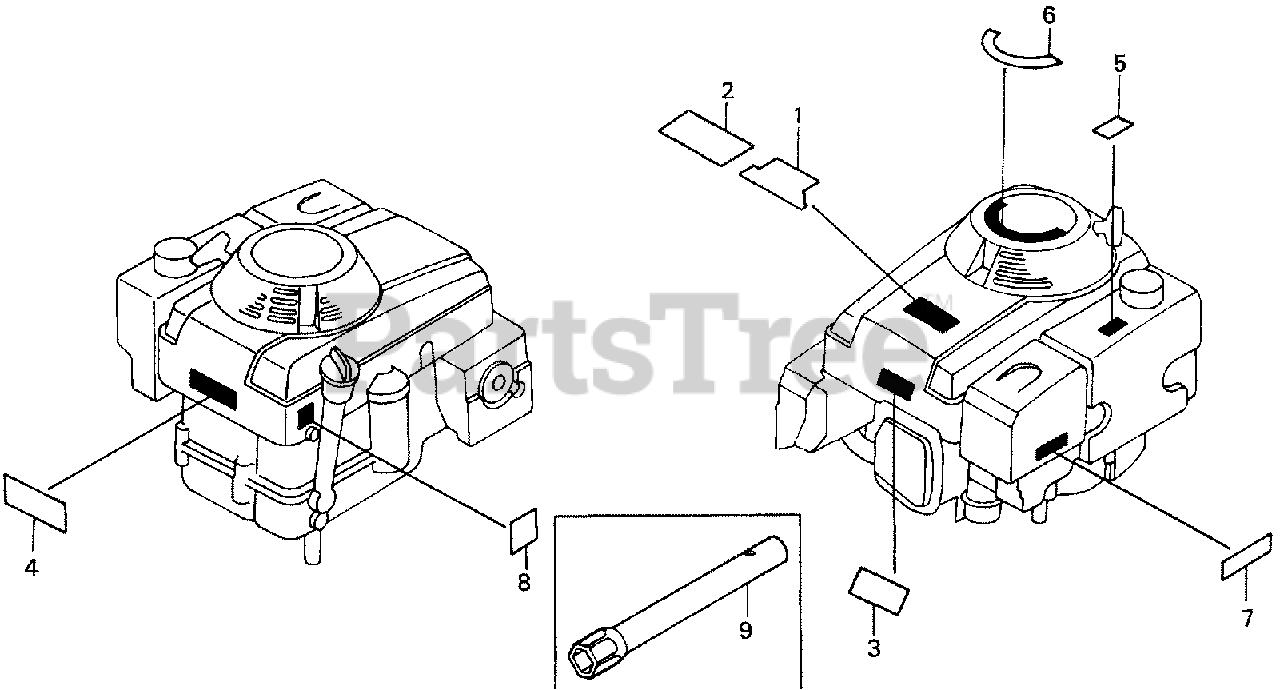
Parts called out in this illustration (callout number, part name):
1	MARK, TOP COVER
4	MARK, CAUTION
5	LABEL, FUEL CAUTION (ENGLISH)
6	MARK, EASY START (ENGLISH)
7	MARK, AIR CLEANER CAUTION
8	MARK, OIL CAUTION
